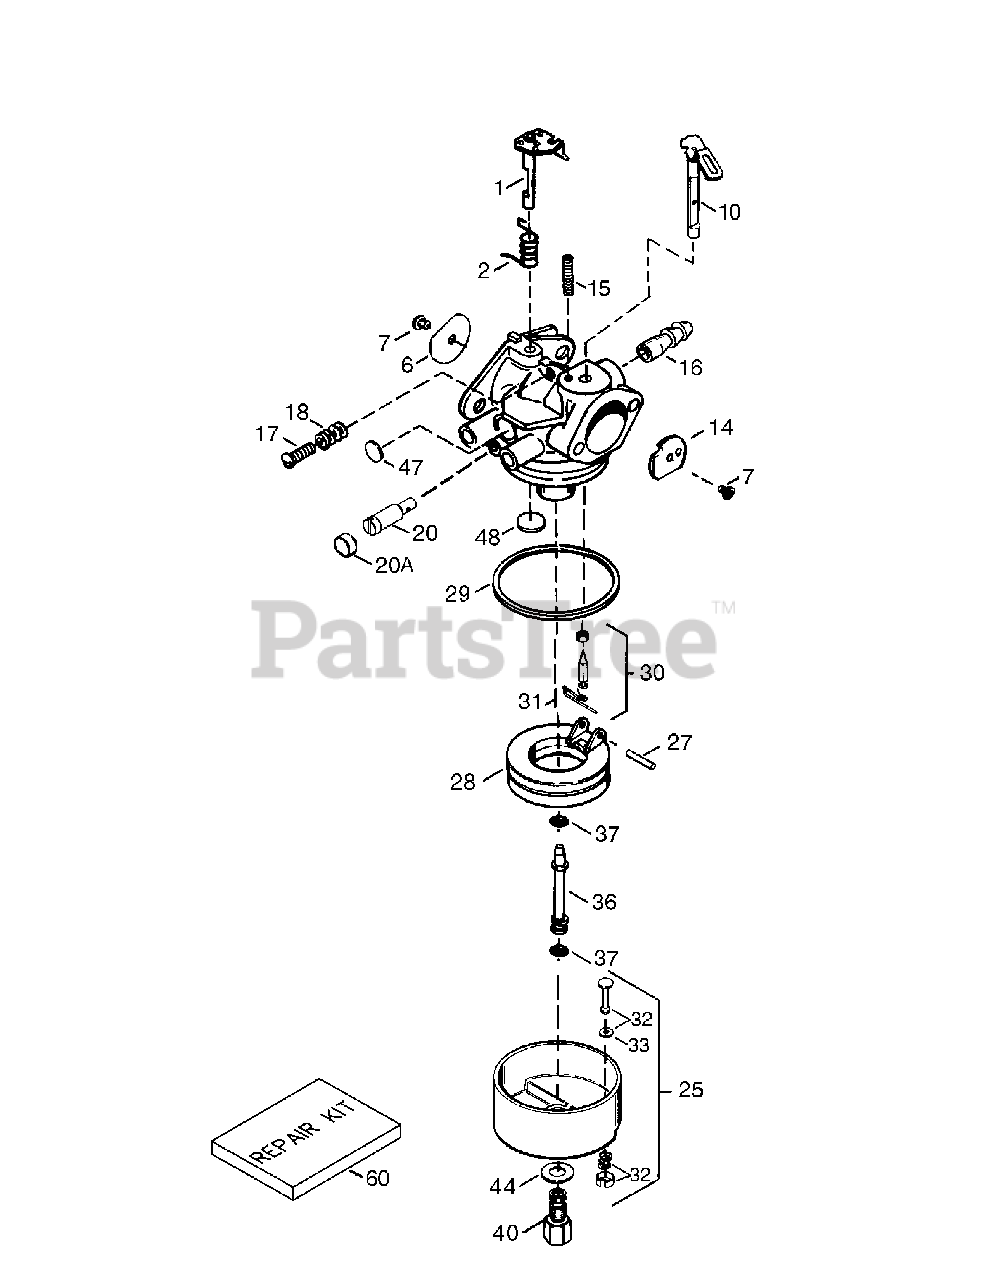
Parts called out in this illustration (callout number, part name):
1	Throttle Shaft & Lever Assy.
2	Throttle Return Spring
6	Throttle Shutter
7	*Shutter Screw
10	Choke Shaft & Lever Assy.
14	Choke Shutter
15	Choke Positioning Spring
16	Fuel Fitting
17	Idle Speed Screw
18	Tension Spring
20	Idle Resrictor Scew
20A	Idle Resrictor Scew Cap
25	Float Bowl Assy.
27	*Float Shaft
28	Float
29	*Float Bowl O-Ring
30	*Inlet Needle, Seat & Clip
31	Spring Clip
32	Bowl Drain Assy.
33	*Plunger Drain Gasket
36	Main Nozzle Tube
37	*Main Nozzle Tube O-Ring
40	High Speed Bowl Nut
44	Bowl Nut Washer
47	*Welch Plug
48	*Welch Plug
60	Repair Kit (Includes Items *)
